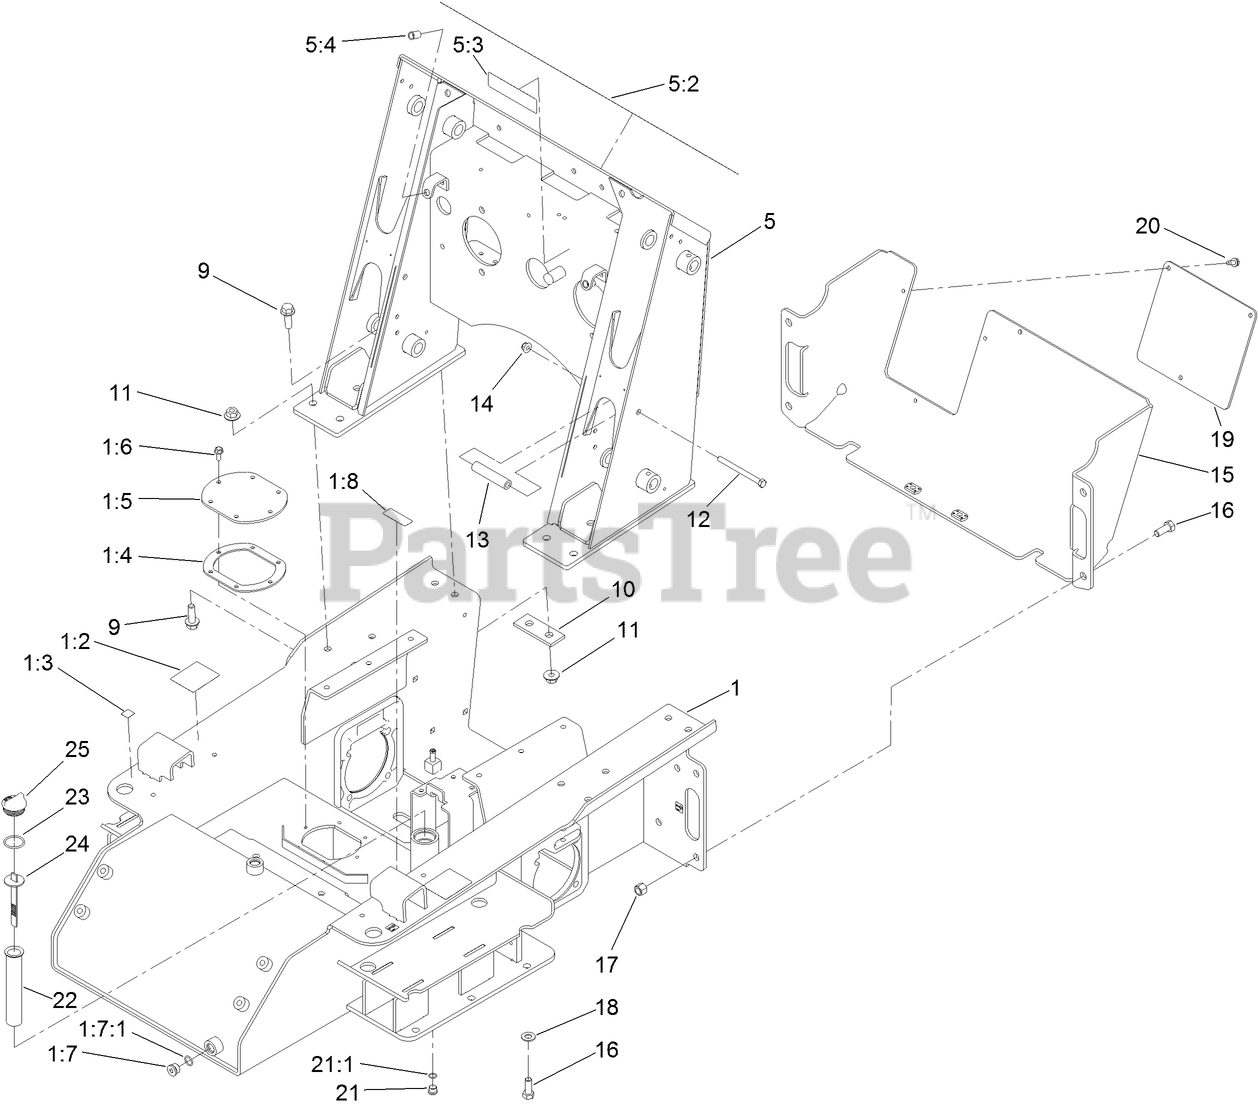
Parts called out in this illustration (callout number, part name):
1	CHASSIS ASM
1:2	DECAL-WARNING
1:3	DECAL-POINT, LIFT
1:4	GASKET-COVER, ACCESS
1:5	COVER-TANK
1:6	SCREW-HHF
1:7	PLUG-HEX
1:7:1	O-RING
1:8	DECAL-OIL, HYD
5	LOADER TOWER ASM
5:2	DECAL-PANEL, CONTROL
5:3	DECAL-DANGER
5:4	NUT-CLINCH
9	SCREW-HHF
10	PLATE-STIFFENER
11	NUT-LOCK, FLANGE
12	SCREW-HH
13	TUBE-SPACER
14	NUT-HF, NI
15	COVER-REAR
16	SCREW-HH
17	NUT-LOCK, NI
18	WASHER-FLAT
19	PANEL-REAR
20	SCREW-THD ROLL, HWH
21	PLUG-HEX, HOLLOW
21:1	O-RING
22	FILTER-SCREEN
23	O-RING
24	DIPSTICK-OIL
25	PLUG-PLASTIC
